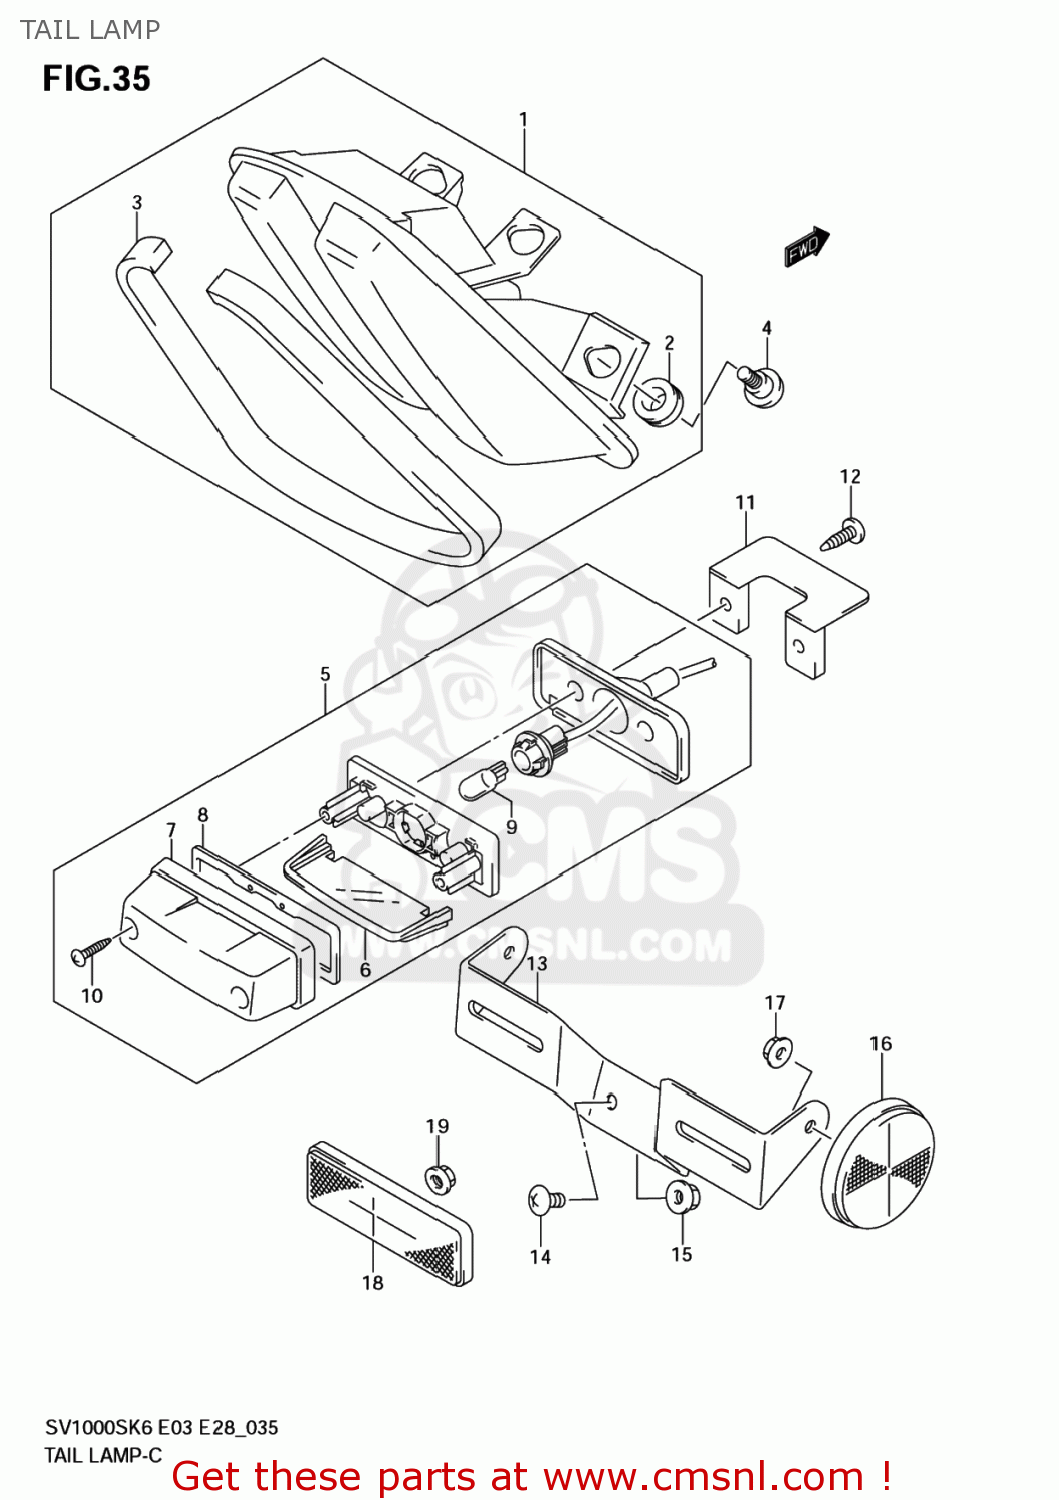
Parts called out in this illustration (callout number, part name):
1	LAMP ASSY,RR COMBINATION
2	CUSHION
3	CUSHION,SEAT TAIL COVER
4	SCREW(6X22.5)
5	LAMP ASSY,LICENSE
6	LENS
7	COVER
8	GASKET (NAS)
9	BULB(12V5W)
10	SCREW
11	BRACKET,LICENSE
12	SCREW
13	BRACKET,LICENSE PLATE
14	SCREW
15	NUT
16	REFLECTOR ASSY,RR SIDE
17	NUT
18	REFLECTOR ASSEMBLY,REAR
19	NUT
